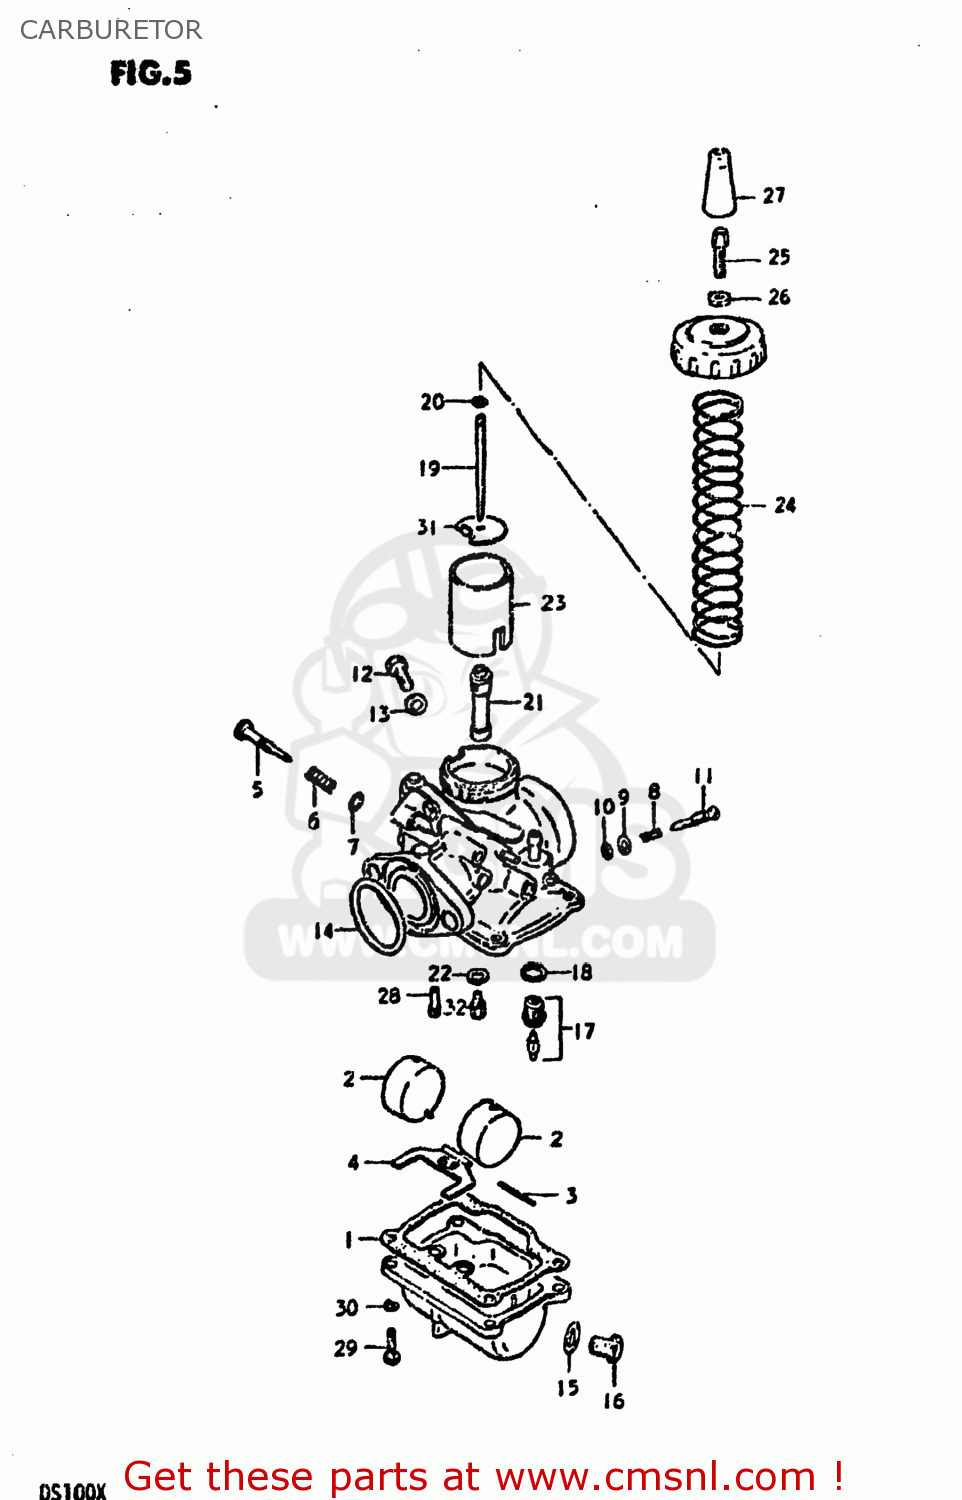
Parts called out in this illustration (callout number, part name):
0	CARBURETOR ASSEMBLY
1	GASKET,FLOAT CHAMBER (NAS)
2	FLOAT
3	PIN,FLOAT
4	PLATE
5	SCREW,THROTTLE STOP
6	SPRING,PILOT
7	O-RING
8	SPRING
9	WASHER,PILOT AIR SCREW
10	O RING
11	SCREW,PILOT AIR
12	BOLT
13	GASKET,THRO VALVE INSPECTION (NAS)
14	O RING
15	GASKET,DRAIN,PLUG (NAS)
16	PLUG
17	VALVE ASSEMBLY,NEEDLE
18	GASKET,VALVE SEAT (NAS)
19	NEEDLE,JET
20	CLIP
21	JET,NEEDLE
22	WASHER
23	VALVE,THROTTLE
24	SPRING, THROTTLE VALVE
25	ADJUSTER,CABLE
26	NUT
27	CAP
28	JET
29	SCREW
30	LOCK WASHER
31	SEAT,THROTTLE VALVE SPRING
32	JET,MAIN 90
